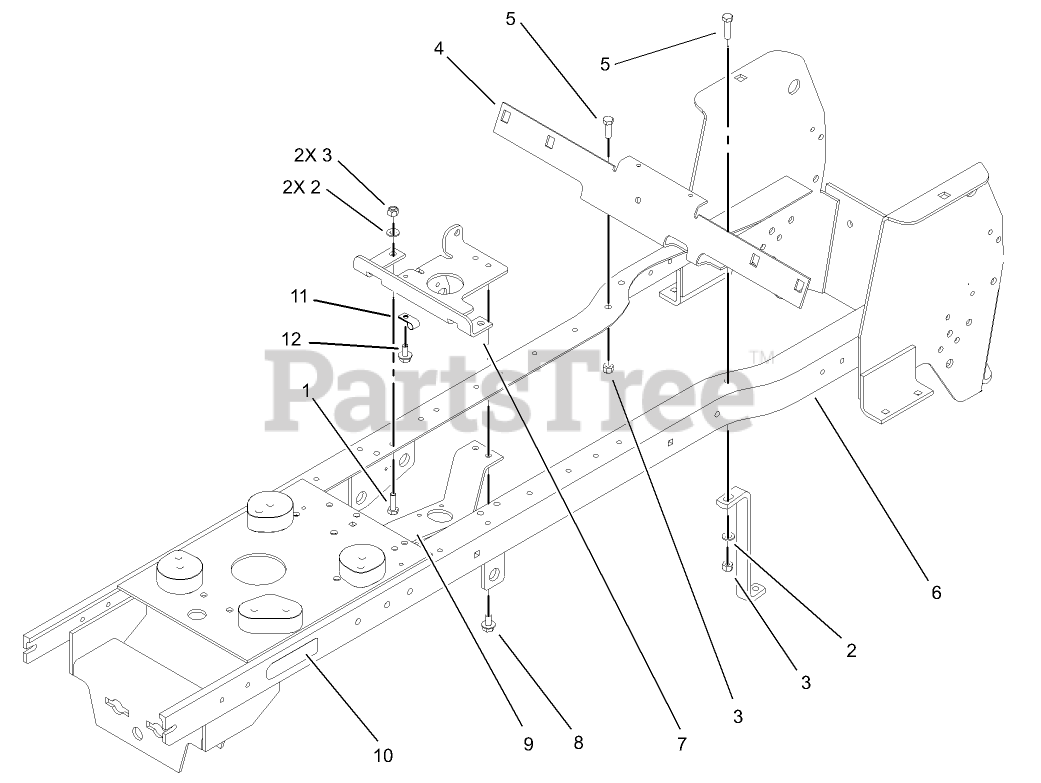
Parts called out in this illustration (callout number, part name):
1	SCREW-HH
2	WASHER-PLAIN
3	NUT-LOCK, NI
5	SCREW-HH
6	FRAME ASM
7	BRACKET-SUPPORT, STEERING
8	SCREW-HWHTF
9	STEERING BRACKET ASM
10	DECAL-ATTACH A-MATIC
11	CLAMP-R
12	SCREW-HWH
